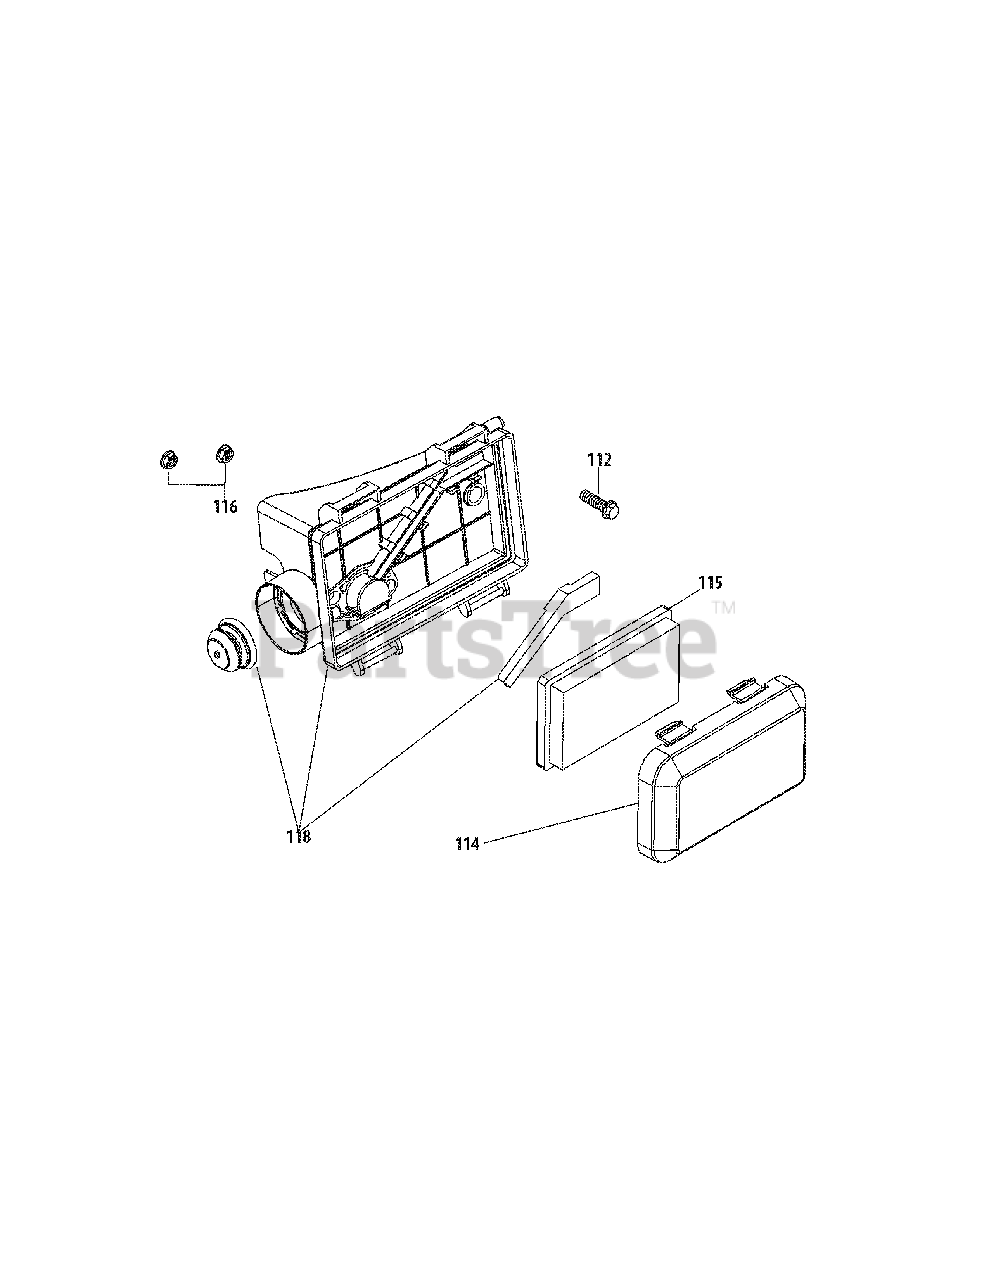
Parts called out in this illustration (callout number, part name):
112	Bolt M6X30 Af Base/Coil/E-Starter
114	Air Filter Cover
115	Air Filter Element, Paper
116	Nut M6X10Mm Starter/Carb/Muff
118	Air Filter Base Assembly
